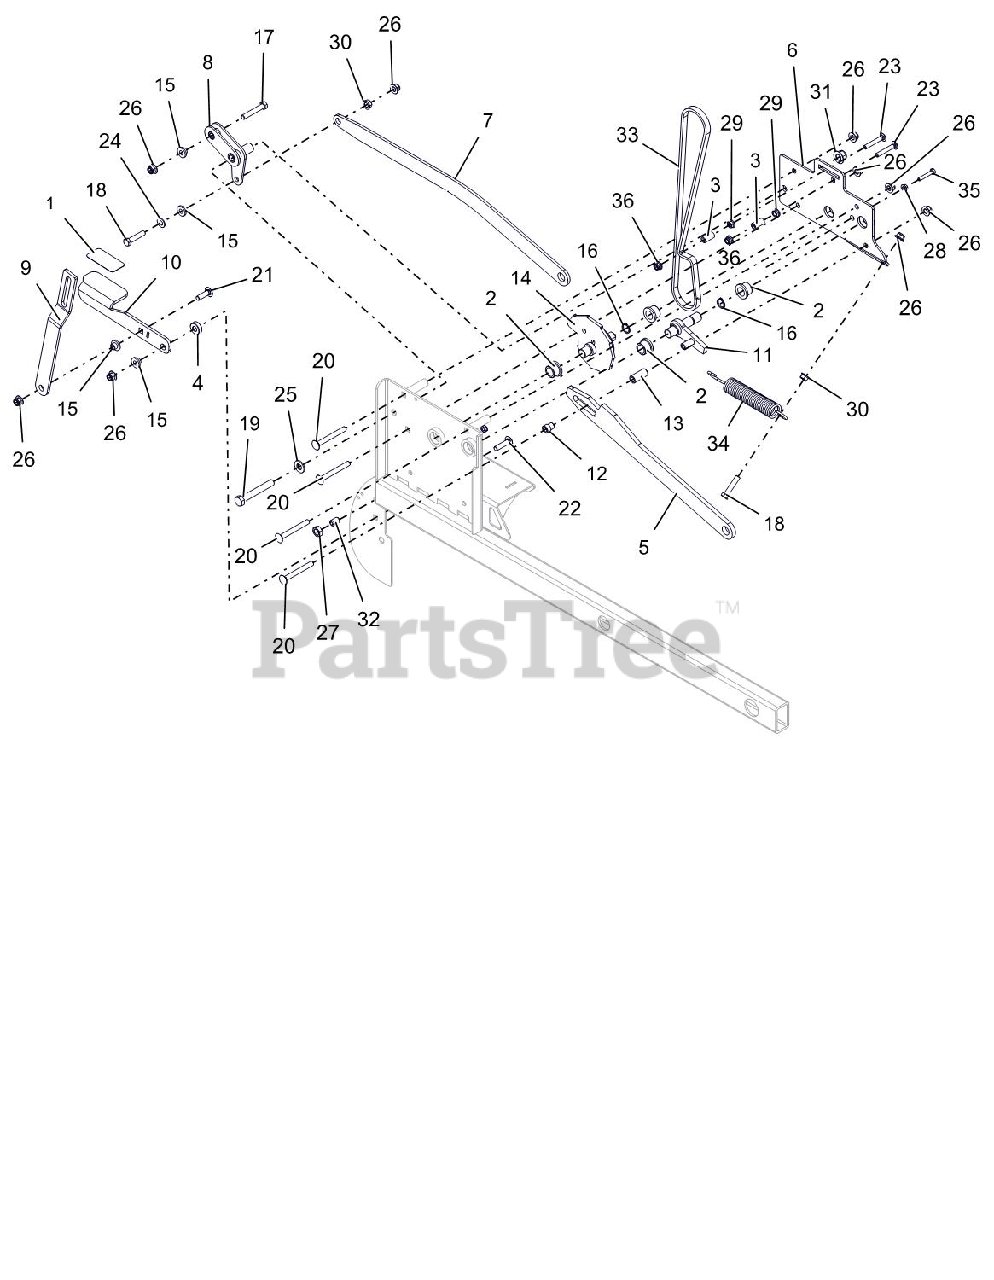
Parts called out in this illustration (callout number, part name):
1	GRIP, PEDAL 1.50 X 3.00
2	BUSHING, FLANGE .75X.75X1.0
3	SPACER .331 X .500 X 1.000
4	SPCR, .375 X 1.00 X .342
5	ARM, CAM CONTACT
6	WLDMT, CAM COVER
7	ARM, PEDAL
8	WLDMT, REAR PEDAL PIVOT
9	LINK, REAR PEDAL
10	PEDAL, DECK LIFT FOOT
11	WLDMT, TRAILER LOCK
12	BSHG, .375 X .75 X 1.00
13	SPCR, .375 X .75 X 1.00
14	WLDMT, 36 PS HOC CAM
15	BSHG-FLG .385X.500X.875X.406
16	RG-RTNG-EXT .689X.078
17	@BLT-HEX .38-16X2.25 GR5 YWZC
18	@BLT-HEX .38-16X1.75 GR5 YWZC
19	@BLT-HEX .50-13X3.50 GR5 YWZC
20	BLT-RDHDSQNK .38-16X3.25 GR5YZ
21	@BLT-RHDSSQNK .38-16X1.25 G5YZ
22	@BLT-RHDSSQNK .38-16X1.50 G5YZ
23	BLT-RDHDSQNKFT .31-18X2.0 G5YZ
24	@WSHR-FL-STL.406X.812X.065 YWZ
25	@WSHR-FL-STL.531X1.06X.095YWZC
26	@NUT-LK-NYL-FLG .38-16 YWZC
27	NUT-JAM .50-13 YWZC
28	@NUT-SPNLK-FLG .25-20 YWZC
29	@NUT-SPNLK-FLG .312-18 YWZC
30	@NUT-SPNLK-FLG .375-16 YWZC
31	@NUT-LK-NYL-FLG .50-13 YWZC
32	BALL SPRING PLUNGER, .500-13
33	BELT, TIMING SHORT
34	SG-TENS .162X1.25X8.25 WLD 25
35	@BLT-HEX .25-20X1.50 GR5 YWZC
36	@NUT-LK-NYL-FLG .31-18 YWZC
